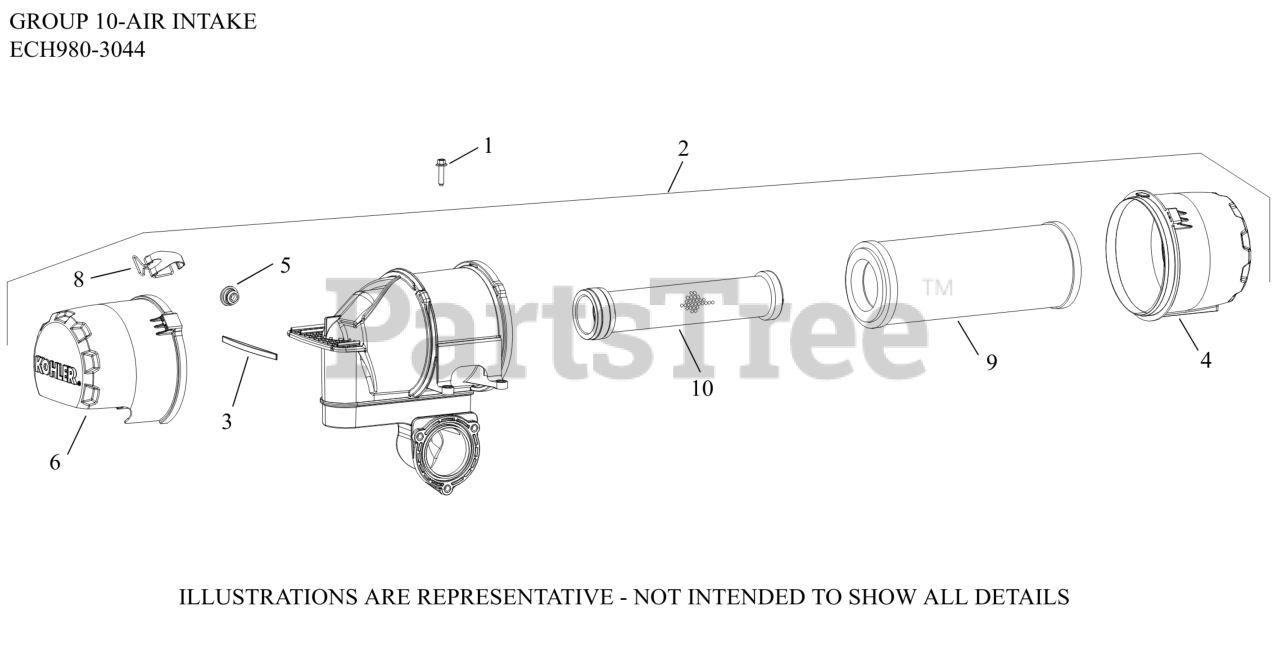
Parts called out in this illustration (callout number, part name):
1	SCREW, FLG M6X1.0X25
2	FILTER ASSEMBLY, AIR
3	DAMPER, FOAM INSERT
4	COVER, AIR FILTER
5	PLUG, HOLE
6	COVER, RAIN CAP
8	CLIP ASSEMBLY
9	ELEMENT, AIR FILTER - PRIMARY
10	ELEMENT, AIR FILTER - SAFETY
14	ELEMENT, PRE-CLEANER
15	ELEMENT, AIR FILTER (LPAC)
23	BASE, AIR CLEANER
